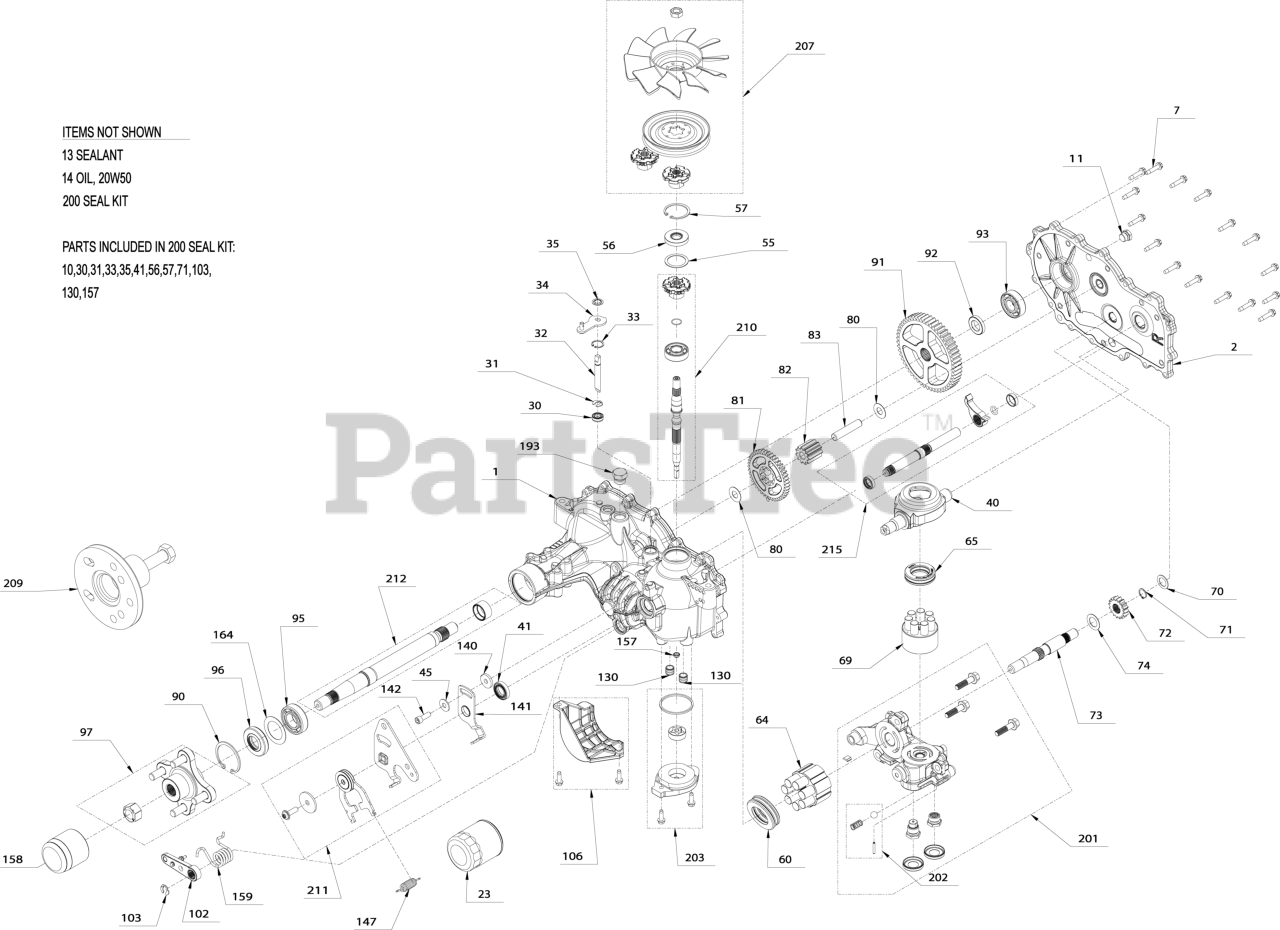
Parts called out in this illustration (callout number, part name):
1	KIT, HOUSING, MAIN, RH, CHRG, CNTL
2	KIT, SIDE COVER, RH
7	SCREW,HEX WASHER 1/4-20X1.125
11	PLUG, EXTERNAL HEX VENT 9/16-18
13	SEALANT TUBE 10.1OZ.
14	FLUID, HYDRO 15W50 QT
14	FLUID, HYDRO 20W50 QT
23	FILTER, HYDRO-GEAR 2800 TRANS
30	SEAL, LIP .375 X .75 X .25
31	RING. RETAINING
33	RING, RET .750
34	ARM, BYPASS
35	RING, RTNG .
40	TRUNNION, SWASHPLATE
41	SEAL, LIP 18X32X7
55	WASHER 1.23X1.56X.04
56	SEAL, LIP 17X40X7
57	RING, RET 1.56 INT
60	HG THRUST BEARING (51462)
64	HG 16CC CYLINDER BLOCK (71579)
65	BEARING. THRUST 30 X 52 X 13
69	ASSY, BLOCK 7 PISTON
70	WASHER .63X1.0X.05
71	RING, RET 62 EXT
72	GEAR, 16T (STEEL)
73	SHAFT, MOTOR
74	WASHER .71 X 1.16 X .04
80	WASHER .5X1.0X.032
81	GEAR, 43T
82	GEAR, 11T (STEEL)
83	JACK SHAFT (PIN)
90	RING, RETAINING
93	KIT, BEARING
95	BEARING, BALL 25.4 X 52 X 15
96	SEAL, LIP
97	KIT, HUB 4 BOLT
102	BRAKE ARM HG 71957
103	CLIP,BRAKE ARM HYDROGEAR 52027
106	KIT, FILTER GUARD
130	TUBE, CHARGE TRIPLE O-RING
141	ARM, NEUTRAL RIGHT
142	SHCS 5/16-24X1 PATCH
147	SPRING, HYDROGEAR P/N 51833
157	KIT, GEROTOR SEAL
158	CAP, AXLE
159	SPRING, TORSION CCW
164	WASHER, 1.355 x 2.035 x .021 FLAT
200	KIT, SEAL
201	KIT, CENTER SECTION RH, CHARGE
202	KIT, CHARGE RELIEF
203	KIT, CHARGE
207	KIT, FAN / PULLEY
209	HUB PULLER 5 BLT HYDGEAR 72320
210	KIT, INPUT SHAFT
211	KIT, RTN BIDIRECTIONAL
212	KIT SHAFT AXLE
215	KIT, OUTBOARD, RH ROT A / LH ROT B
